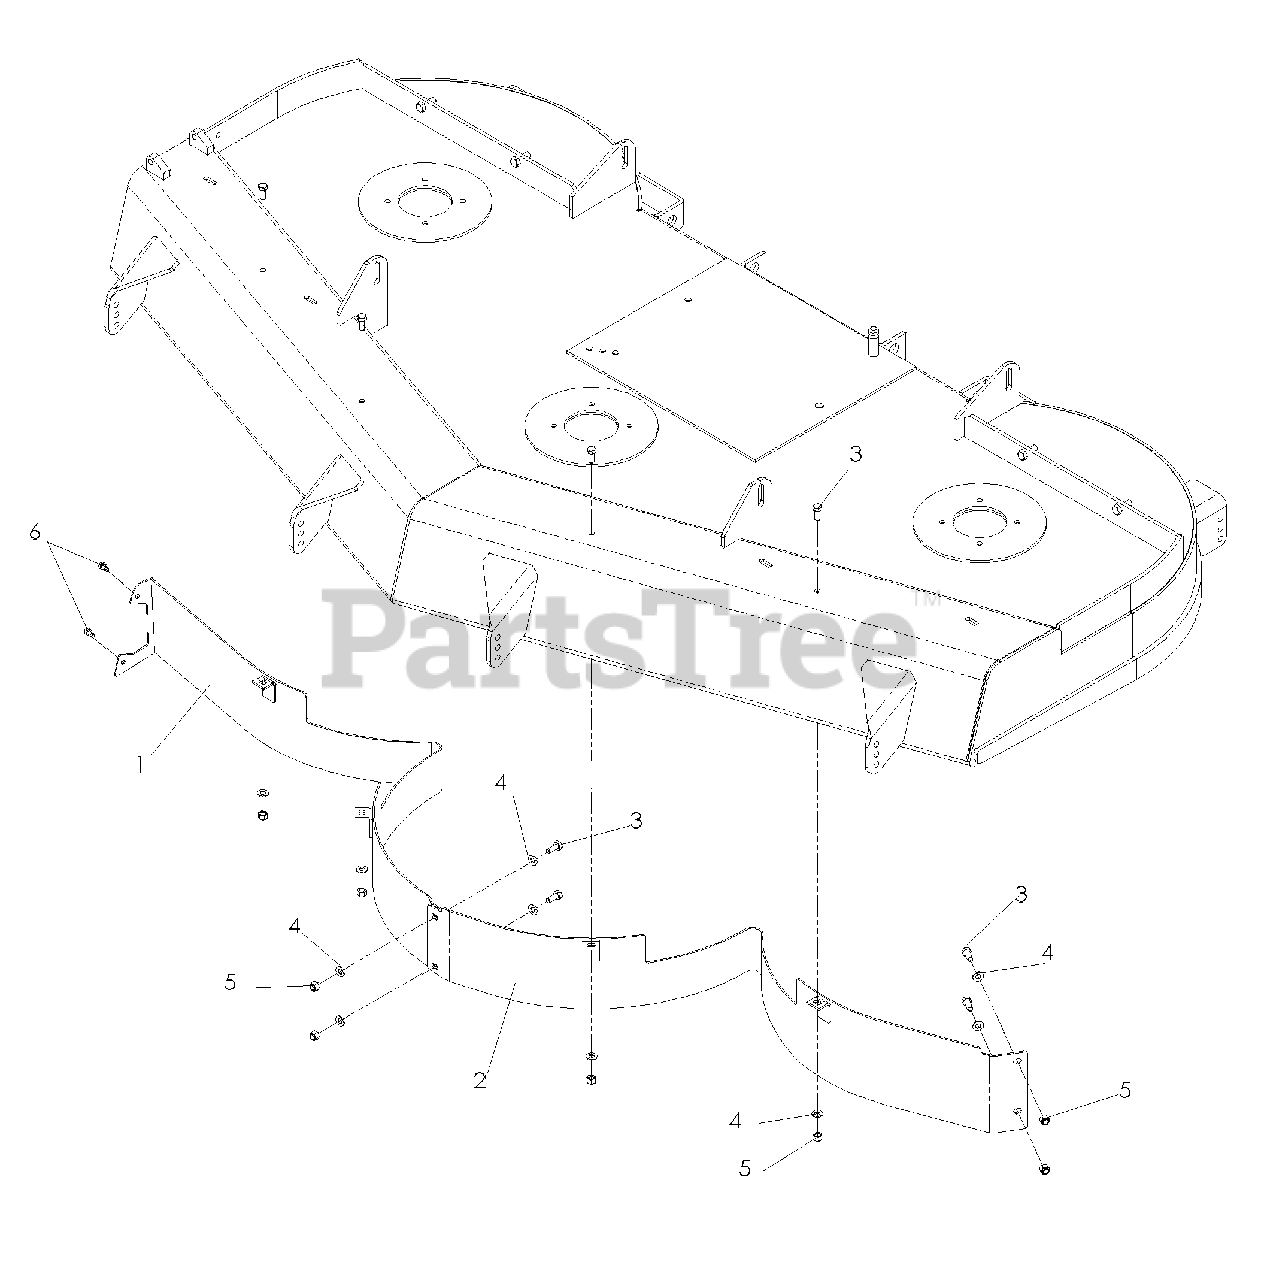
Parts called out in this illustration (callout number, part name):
1	BAFFLE, FRONT, RT
2	BAFFLE, FRONT, LT
3	HCS 5/16-18 x 3/4
4	WASHER 5/16 FLAT SAE
5	NUT 5/16-18 HEX NYLOC
6	SCREW 1/4-20, SLF TAP
